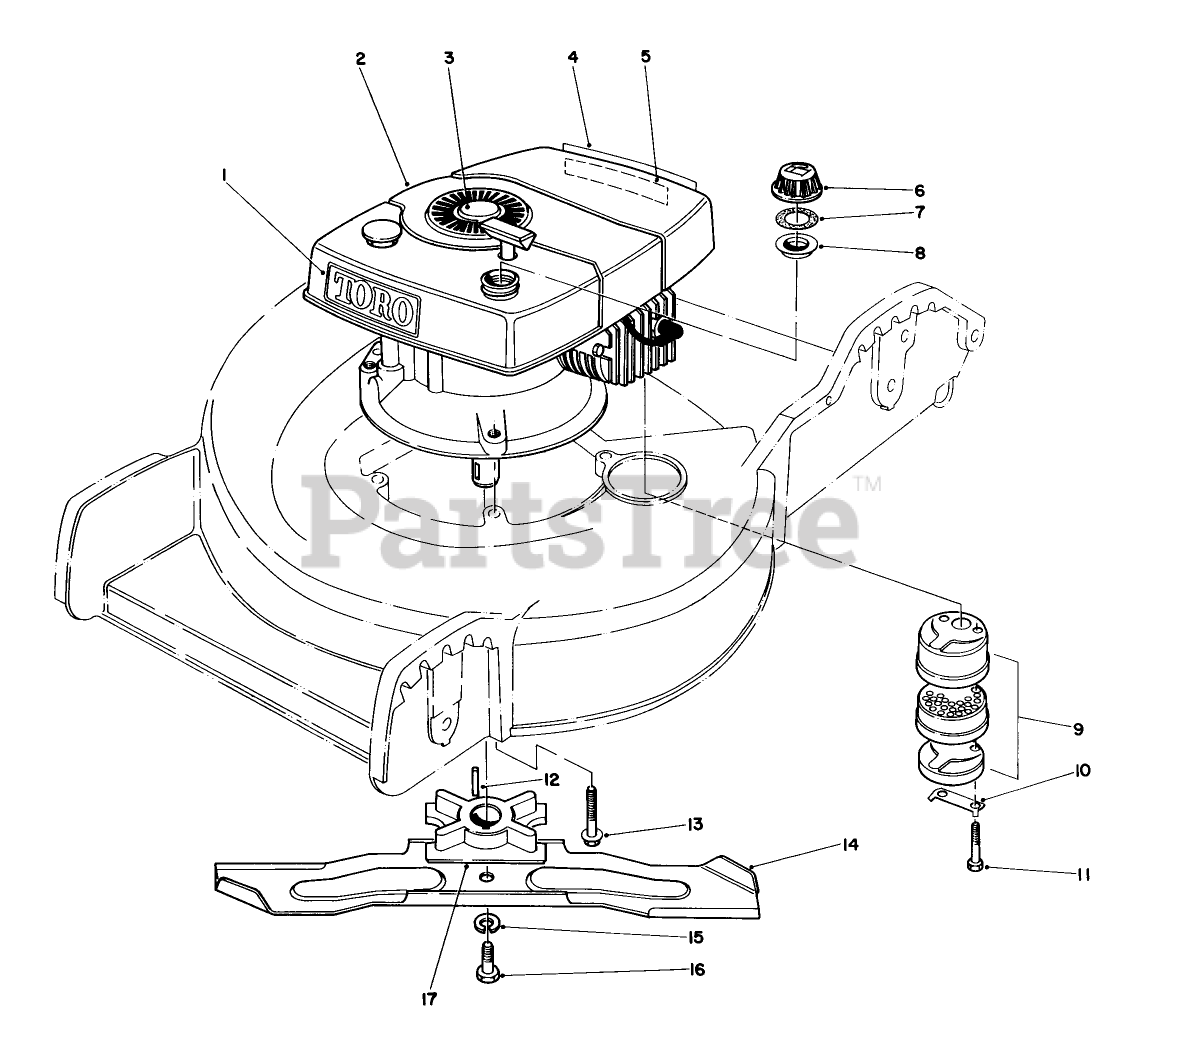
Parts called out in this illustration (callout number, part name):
1	Decal Tow
2	Engine
3	Plug Button
4	Decal-Primer
5	Decal Maintenance
6	Gas Cap Assembly (Incl.Ref. #7 &8)
7	GASKET
8	GAS CAP BAFFLE
9	Muffler Assembly (Incl. Ref.#10 & 11)
10	CLIP - LOCKING
11	SCREW-HH
12	KEY-SQUARE
13	3/8-16 X 2 CAPSCREW
14	Blade
15	WASHER-LOCK
16	SCREW-HH
17	Blade Retainer
